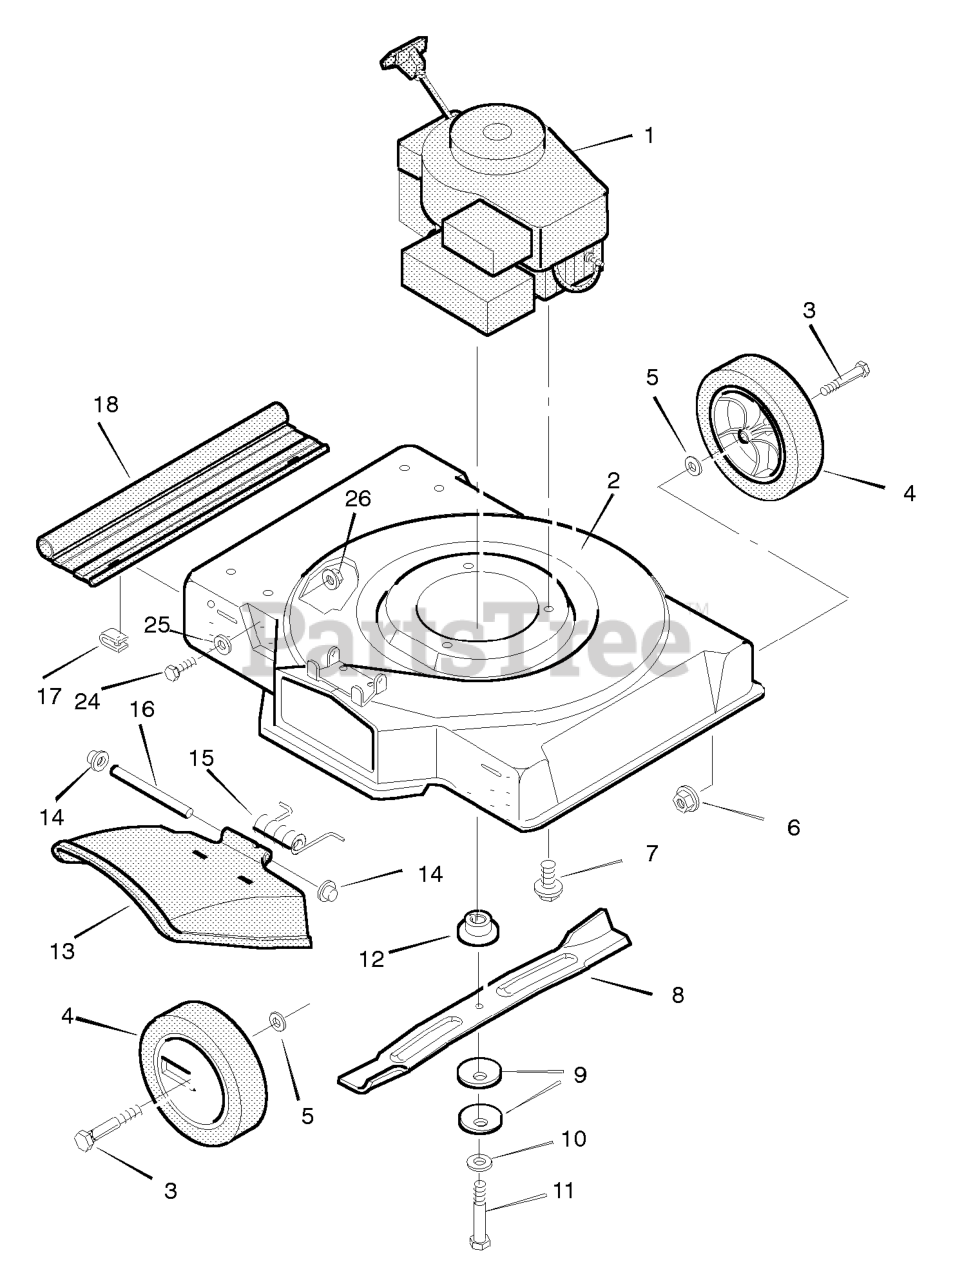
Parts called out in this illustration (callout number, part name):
1	Engine *
2	Housing, For Non- Folding Handle
3	Bolt, Axle
4	Wheel and Tire *
6	Locknut, Flange
7	Bolt, Engine
9	Washer, Belleville
11	Bolt, Hex
12	Adapter, Blade
13	Deflector, Chute
14	Push- On Cap
16	Pin, Pivot
17	Retainer
18	Deflector, Rear
24	Bolt, Hex
26	Locknut, Flange
